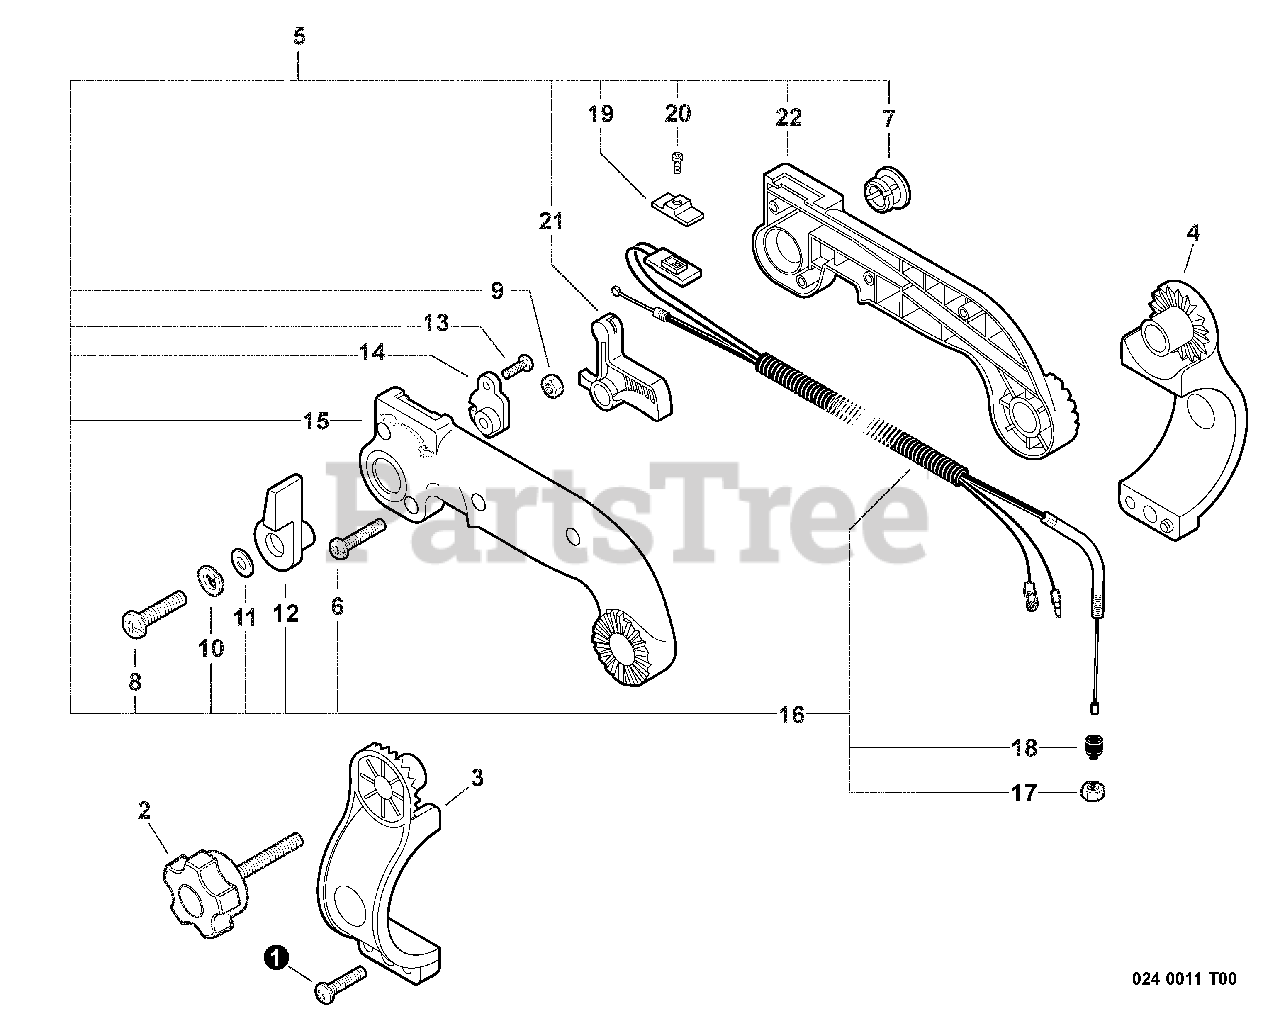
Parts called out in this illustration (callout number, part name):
1	SCREW - 5X20
2	THUMBSCREW
3	BRACKET - LEFT
4	BRACKET - RIGHT
5	CONTROL HANDLE KIT
6	SCREW - 4X22
8	SCREW - 6X20
9	LOCKNUT - 6
10	LOCKWASHER - 6
11	WASHER - 6
12	CONTROL, THROTTLE
13	SCREW - 4X10
14	BRACKET, THROTTLE
15	HANDLE, CONTROL - LEFT
16	CONTROL CABLE ASSY
17	LOCKNUT - 6
18	CAP, DUST
19	KNOB, SWITCH - ORANGE
20	SCREW - 3X10
21	TRIGGER, THROTTLE
22	HANDLE, CONTROL - RIGHT
